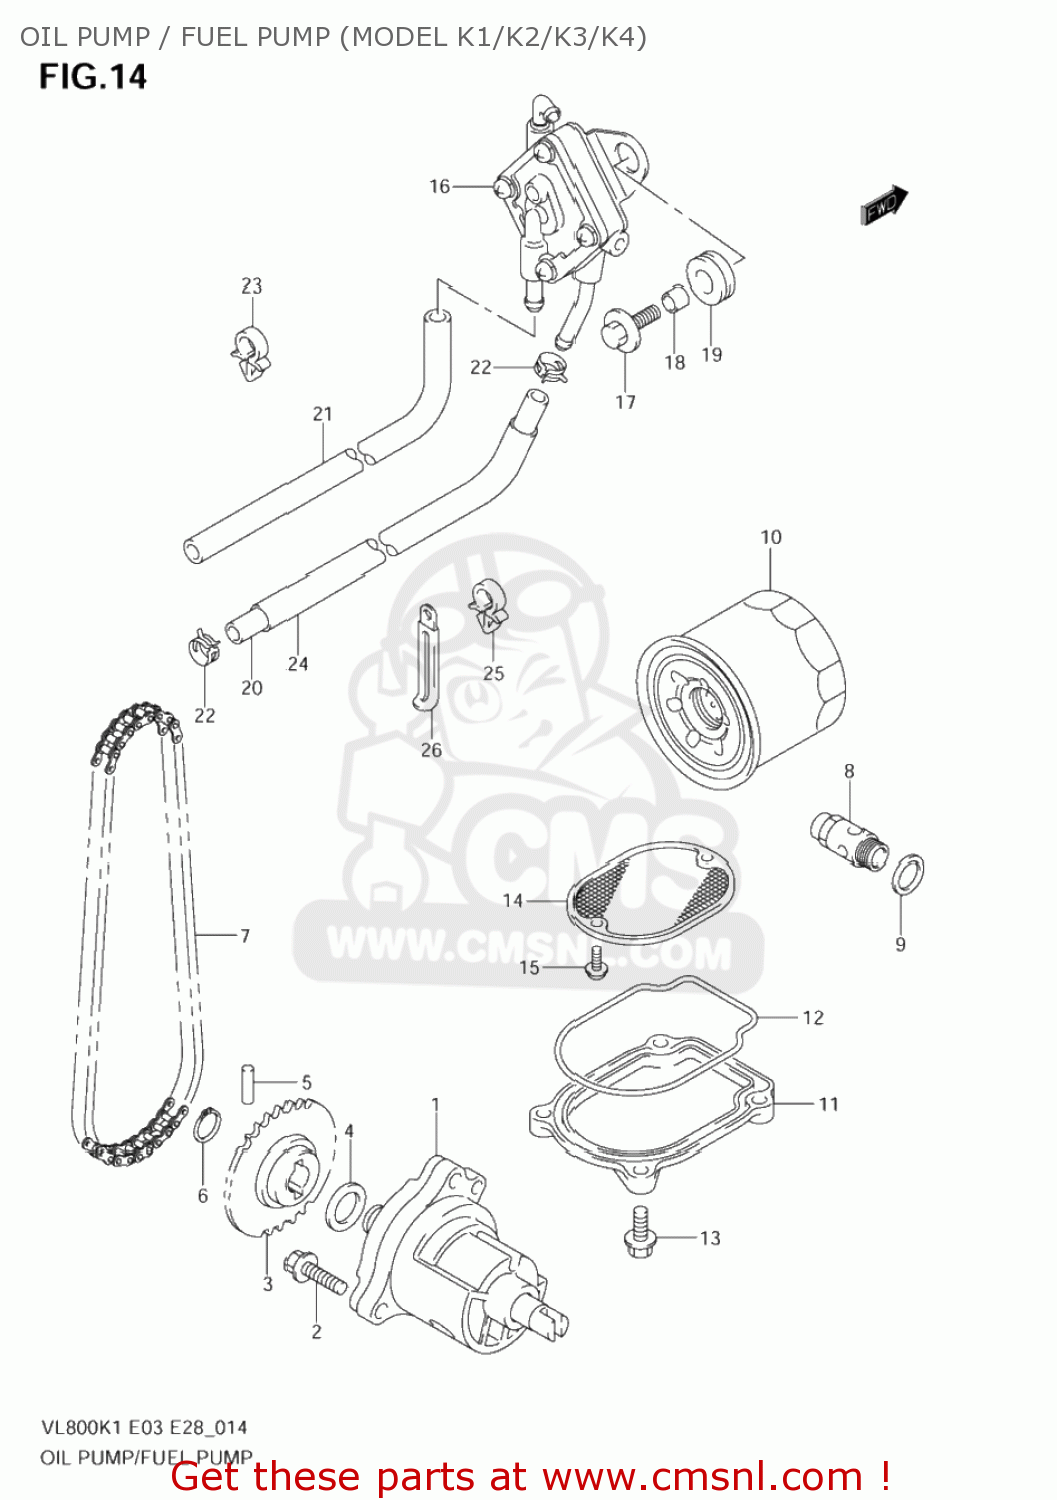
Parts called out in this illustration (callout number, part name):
1	PUMP ASSY,ENGINE OIL
2	BOLT
3	SPROCKET,OIL PUMP DRIVEN
4	SHIM(12X20X0.5)
5	PIN(5X18)
6	CIRCLIP,12 MM
7	CHAIN,OIL PUMP DRIVE
8	VALVE ASSY,OIL RELIEF
9	GASKET(16X22X2) (NAS)
10	FILTER ASSY,EN
11	CAP,OIL STRAINER
12	O RING,OIL STRAINER CAP
13	BOLT
14	STRAINER,ENGINE OIL
15	SCREW
16	PUMP ASSY,FUEL
17	BOLT(6X25)
18	SPACER(6.5X10X11.6)
19	CUSHION
20	HOSE,FUEL PUMP & CARB
21	HOSE(4.5X8.5,6X9.5,L:600)
22	CLIP
23	CLAMP
24	PROTECTOR,FUEL HOSE
25	CLAMP
26	CLAMP(L:120 T:1.0)
